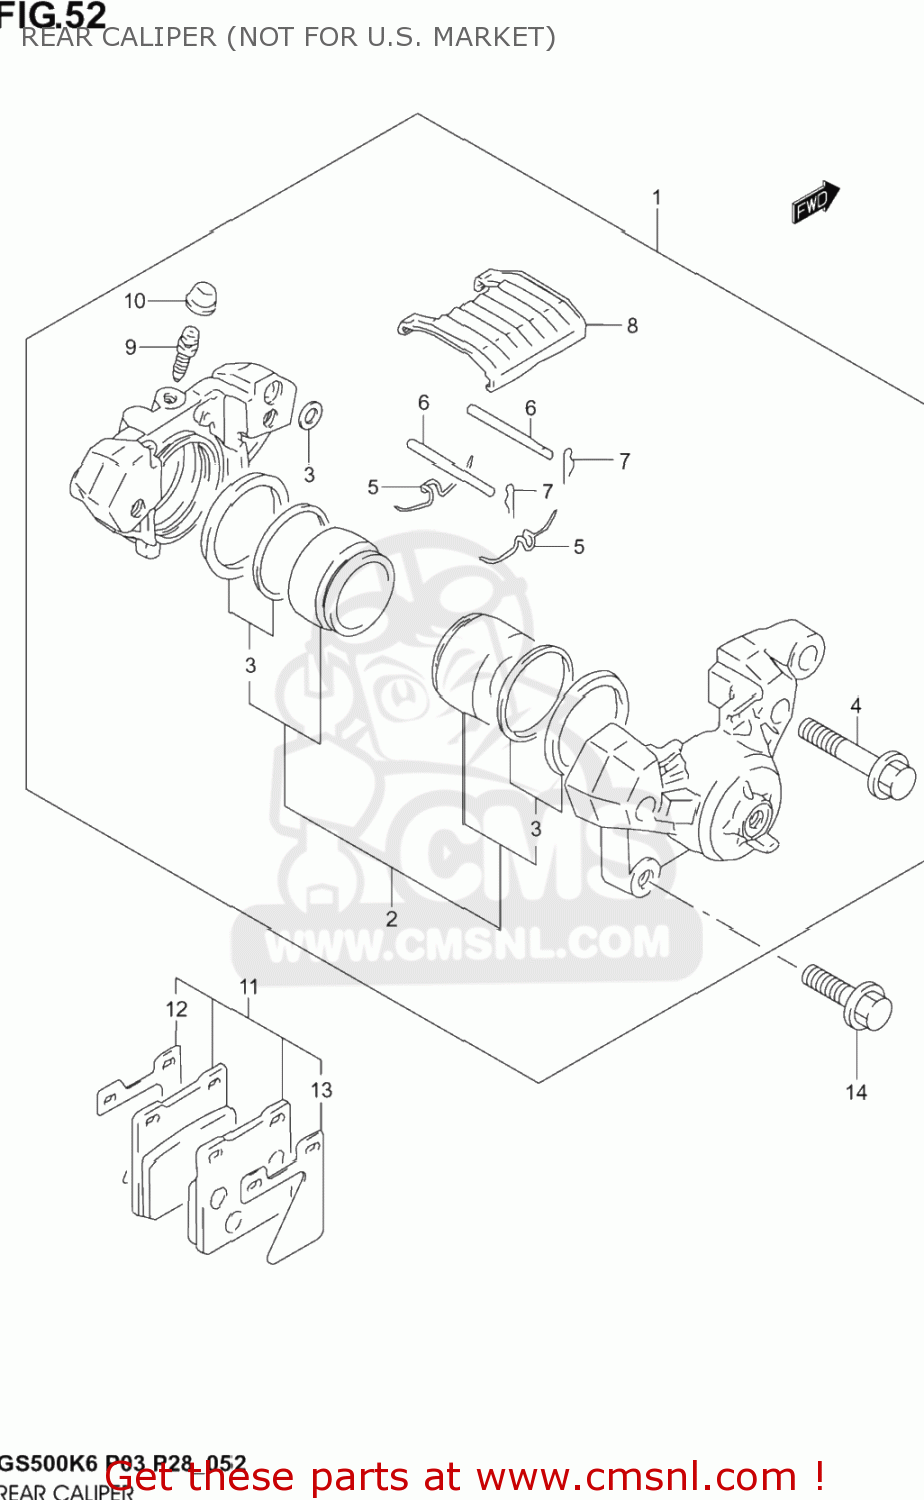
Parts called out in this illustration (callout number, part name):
1	CALIPER ASSY,RR
2	PISTON SET
3	SEAL SET,PISTON
4	BOLT,HOUSING
5	SPRING
6	PIN,PAD
7	CLIP,PAD PIN
8	COVER
9	BLEEDER
10	CAP,BLEEDER PLUG
11	PAD & SHIM SET (NAS)
12	SHIM,INNER
13	SHIM,OUTER
14	BOLT
